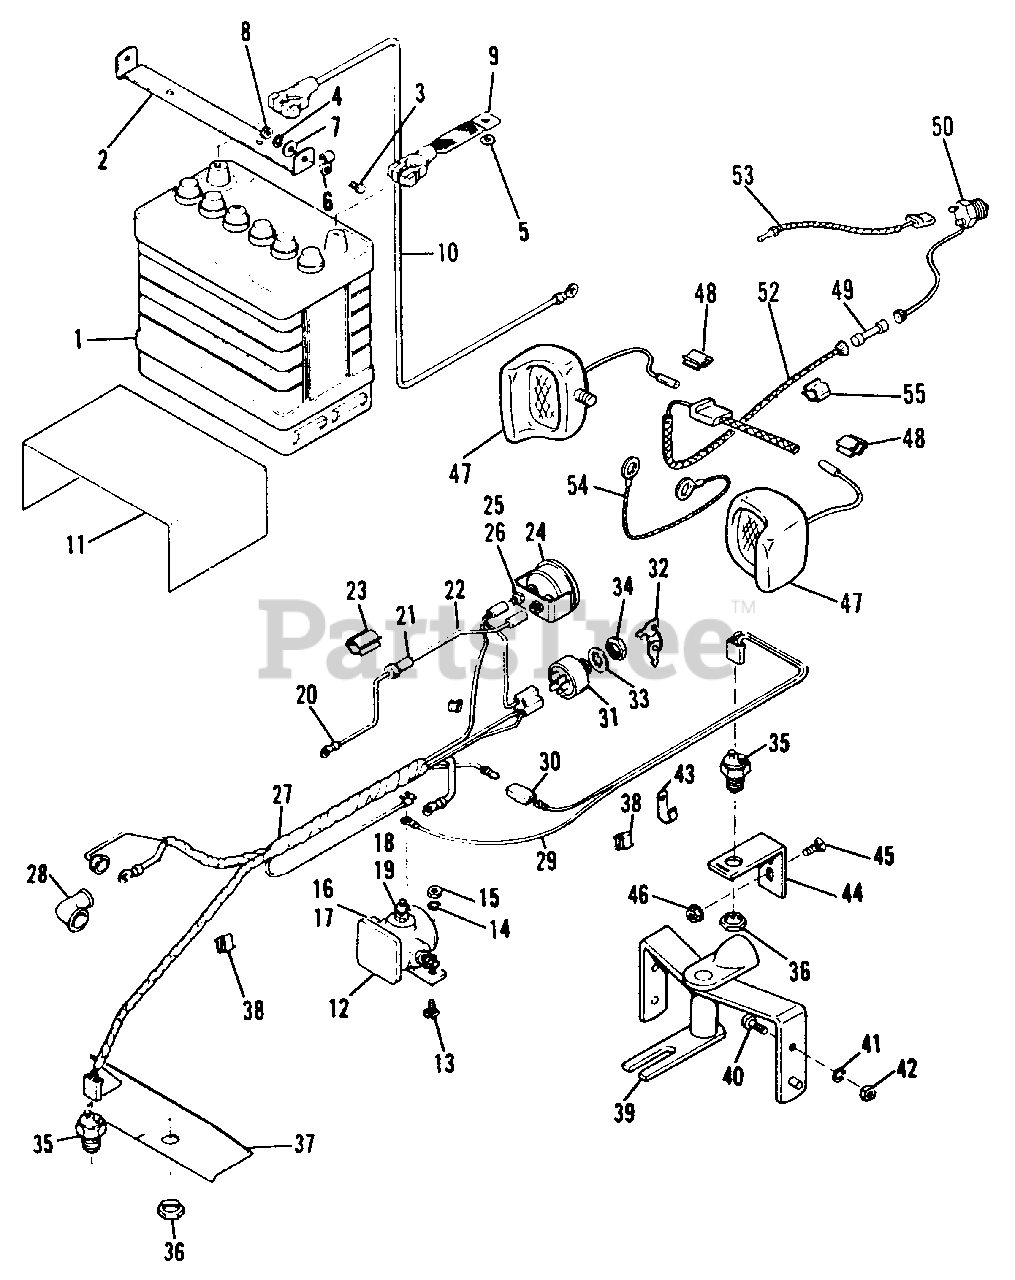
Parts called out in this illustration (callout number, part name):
2	Hold Down, Battery
3	Capscrew, Hex, 1/4"-20 x 3/4" lg.
4	Lockwasher, 1/4"
5	Lockwasher, 1/4"
7	Washer, Plain, 1/4"
8	Nut, Hex, Full, 1/4"-20
9	Cable, Battery to Ground
10	Cable, Battery to Solenoid
11	Battery Insulation
13	Bolt, Carriage, 1/4"-20 x 5/8" lg.
14	Lockwasher, 1/4"
15	Nut, Hex, Full, 1/4"-20
16	Lockwasher, 5/16"
17	Nut, Hex, Full, 5/16"-18
18	Lockwasher, Shakeproof #10
19	Nut, Hex, Full, #10-32
20	Wire, Solenoid to Neg.
21	Fuse, 7-1/2 AMP
22	Wire, Neg. Ammeter to Solenoid
23	Clip, Fuse
25	Lockwasher, Shakeproof, #10
26	Nut, Hex, Full, #10-32
27	Harness Assembly
28	Cover, Terminal
29	Wire, Safety Switch
30	Insulated Connector
31	Switch, Ignition
32	Key & Ring Assembly
33	Lockwasher, Int. 5/8"
34	Nut, Hex, Special
35	Switch, Safety
36	Nut, Pal, 9/16"-18
37	Shield, Heat
38	Clip, Speed
39	Pivot Assembly
40	Capscrew, Hex, 5/16"-18 x 3/4" lg.
41	Lockwasher, 5/16"
42	Nut, Hex, Full, 5/16"-18
43	"J" Clip, Open
45	Bolt, Carriage, 1/4"-20 x 3/4" lg.
46	Nut, Flange, 1/4"-20
47	Drive Light Assembly
48	Clip, Speed
49	Fuse, 20 AMP
50	Switch, Toggle
53	Wire, Lead
55	Clip, Wire
